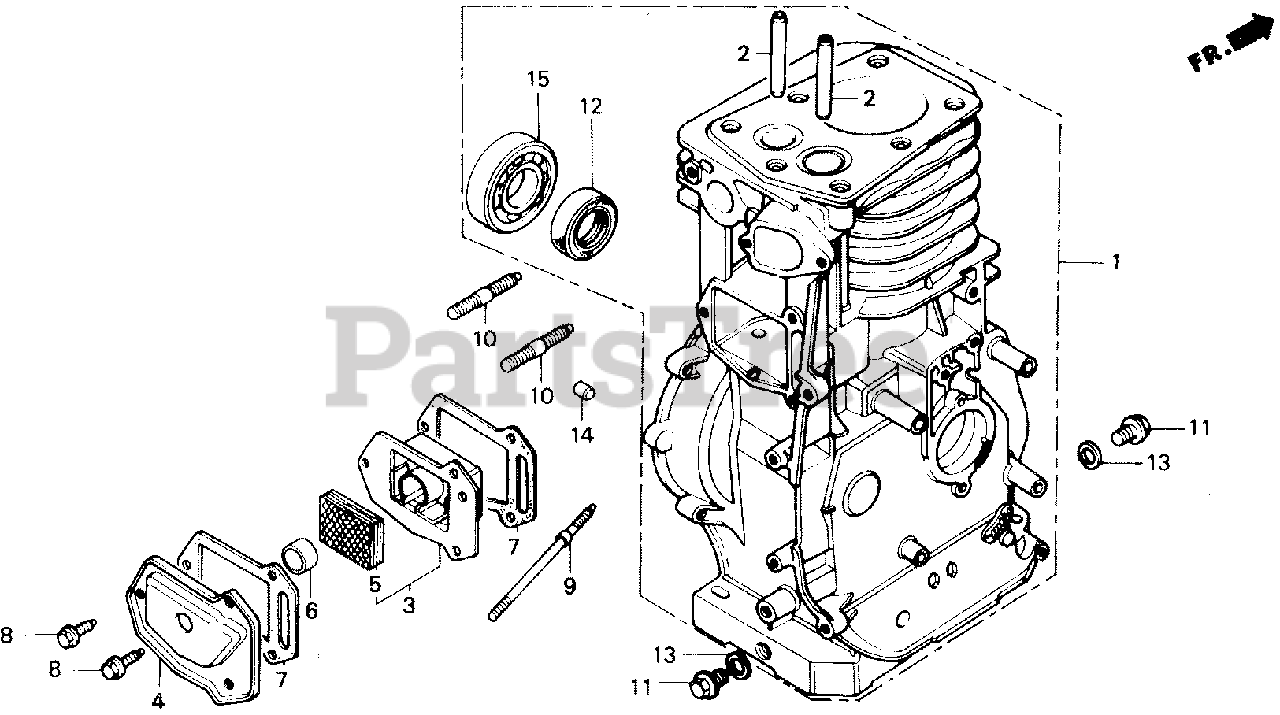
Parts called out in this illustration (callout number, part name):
1	CYLINDER ASSY.
2	GUIDE, VALVE (OVER SIZE)
3	CASE, BREATHER
4	COVER, TAPPET ROOM
5	FILTER, BREATHER
6	SEAL, BREATHER
7	GASKET, TAPPET COVER
8	BOLT, FLANGE (6X12) (CT200)
9	BOLT, STUD (6X89)
10	BOLT, STUD (8X35)
11	BOLT, DRAIN PLUG (12X15)
12	OIL SEAL (25X41X6)
13	WASHER, DRAIN PLUG (12MM)
14	PIN, DOWEL (8X14)
15	BEARING, RADIAL BALL (6205)
